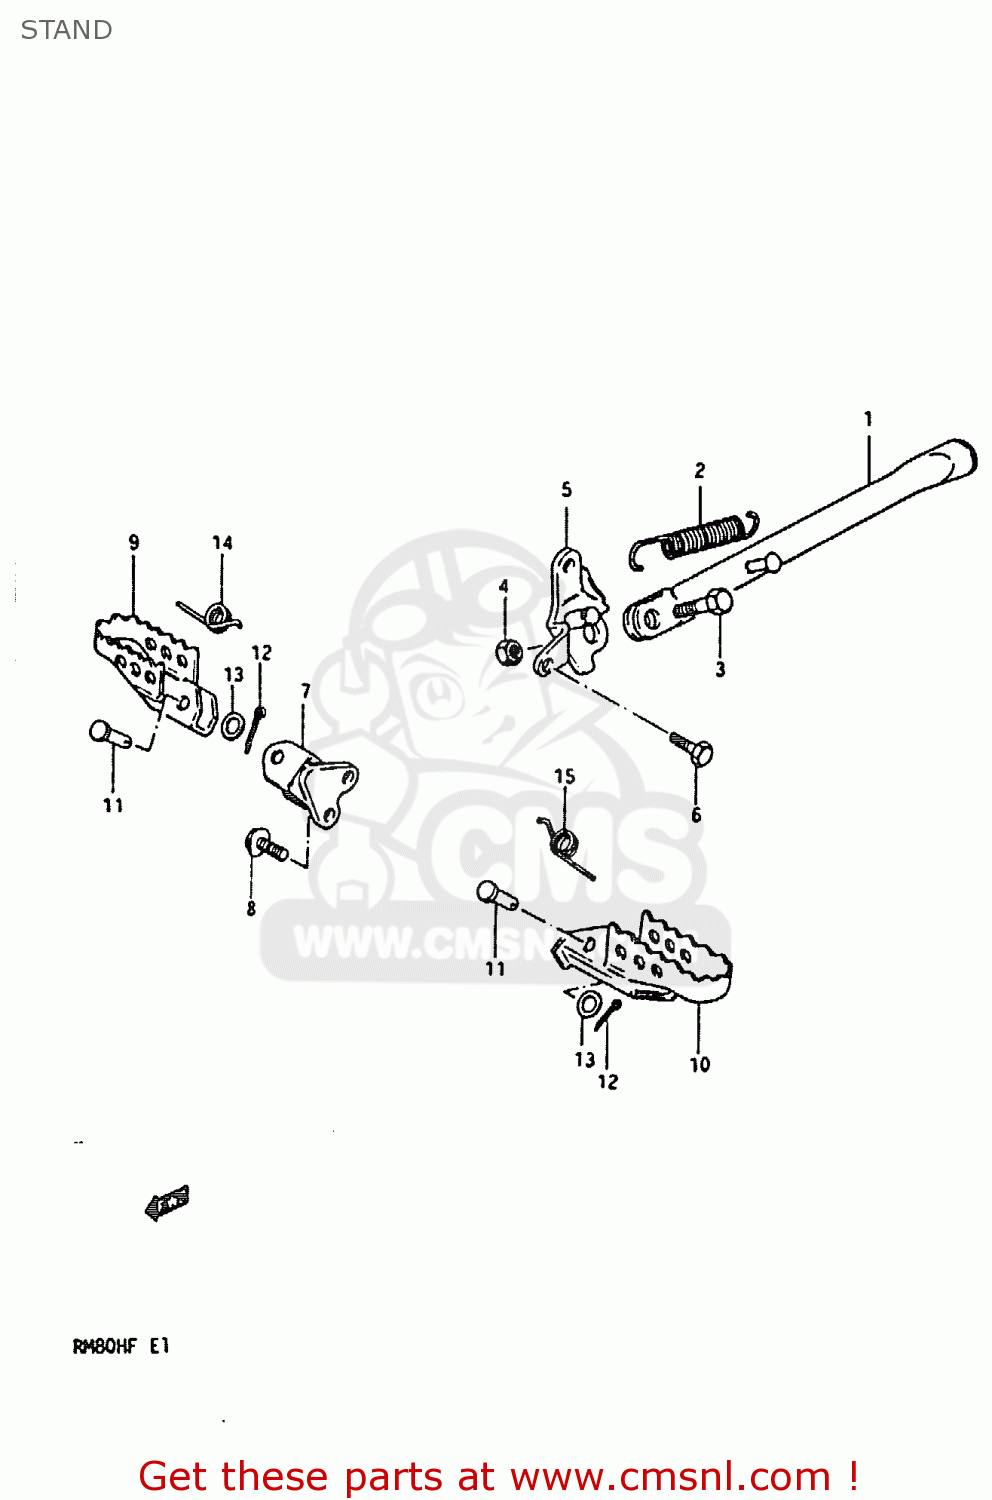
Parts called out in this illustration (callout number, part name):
1	STAND, PROP (BLUE)
2	SPRING
3	BOLT(10X30)
4	NUT
5	BRACKET, PROP STAND (BLUE)
6	BOLT
7	HOLDER, FOOTREST RH (BLUE)
8	BOLT
9	FOOTREST
10	FOOTREST
11	PIN
12	PIN 20X20
13	WASHER
14	SPRING, RH
15	SPRING,FOOTREST,LEFT
